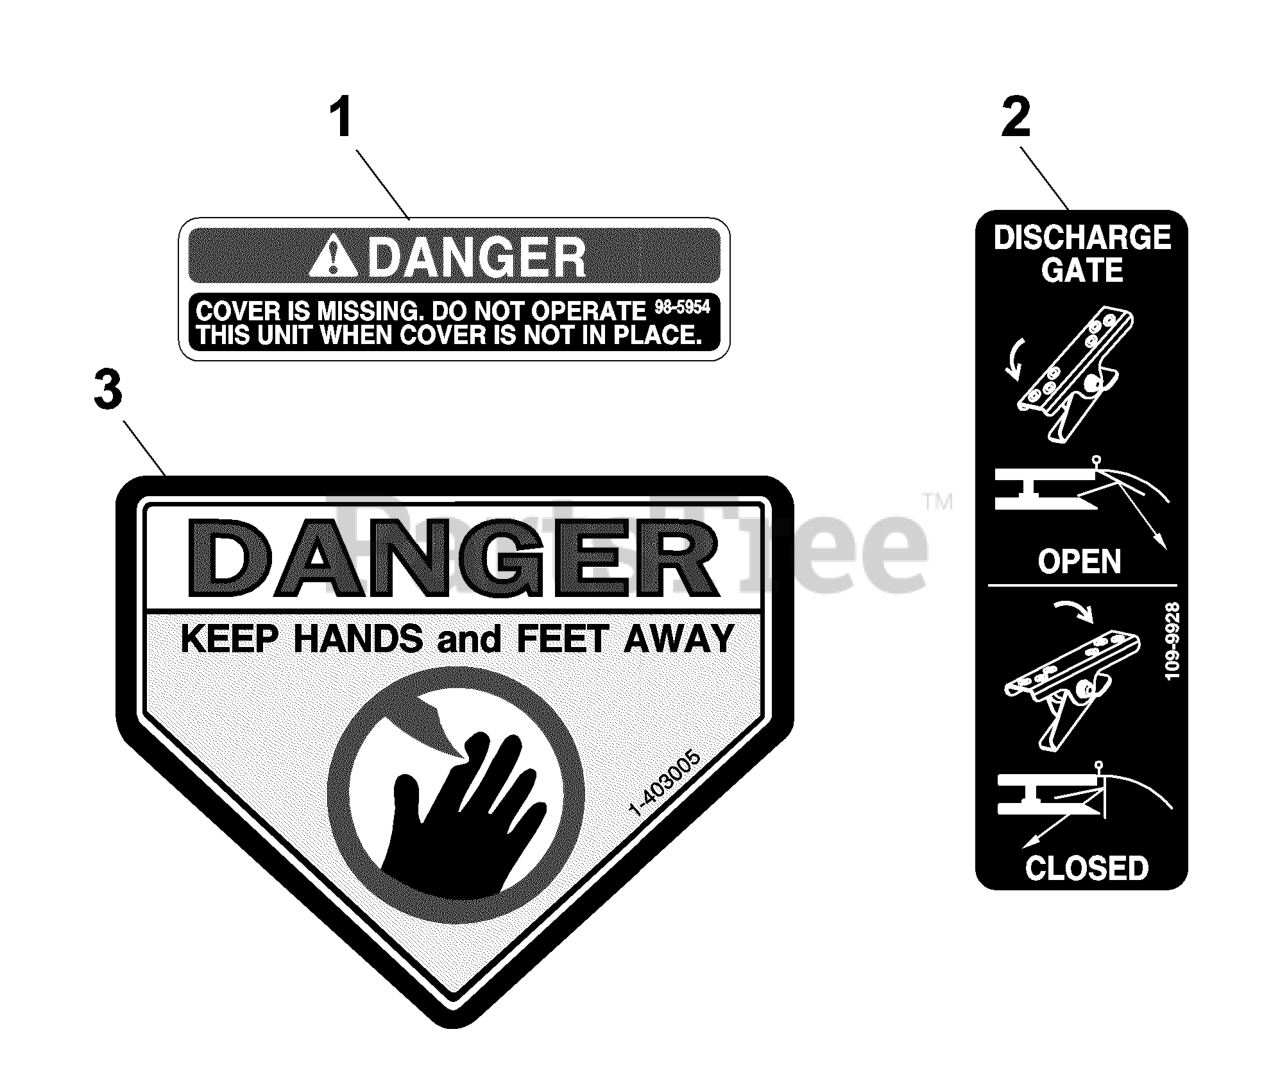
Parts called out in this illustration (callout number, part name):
1	DECAL-COVER, MISSING
2	DECAL,OCDC OPERATION
3	DECAL-DANGER
